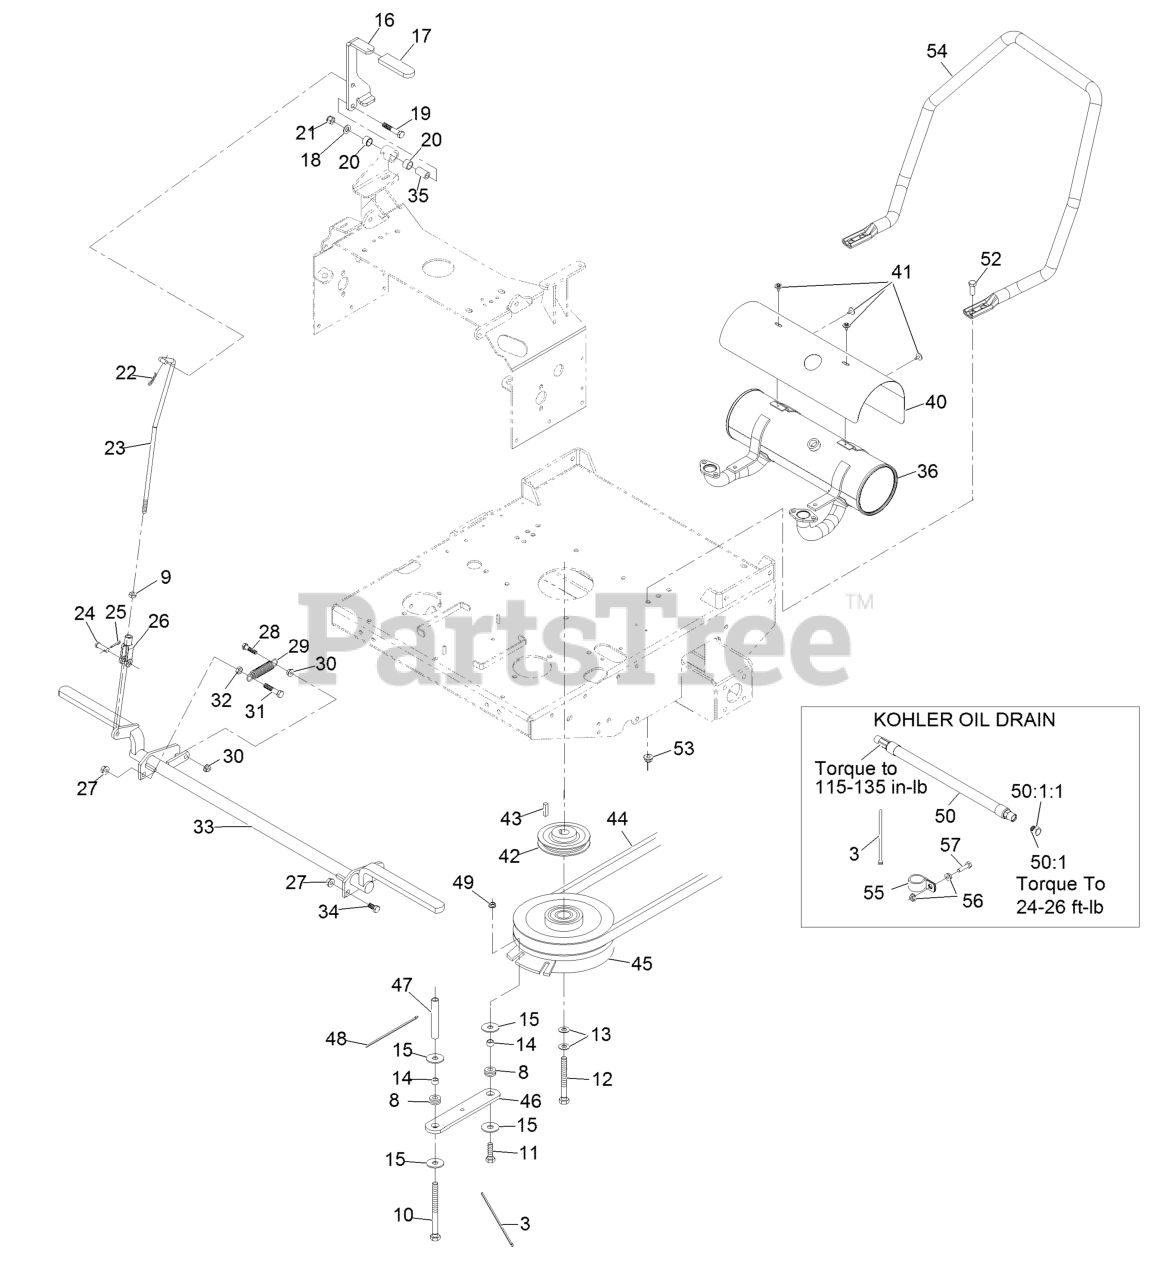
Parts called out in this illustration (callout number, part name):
3	TIE-PLASTIC
8	GROMMET
9	NUT-HJ
10	SCREW-HH
11	SCREW-HH
12	SCREW-HH
13	WASHER-SPRING
16	LEVER,PRK BRK W/DECALS
17	GRIP-LEVER
18	WASHER-FLAT
19	SCREW-HH
20	SLEEVE-BUSHING
21	NUT-LOCK, NI
22	PIN-COTTER
23	LINKAGE, PARK BRAKE
24	PIN-CLEVIS
25	PIN-COTTER
26	YOKE-LINKAGE, BRAKE
27	NUT-HHF, WHIZ
28	SCREW-HH, SPECIAL
29	SPRING-IDLER
31	SCREW-HH
32	NUT-JAM
33	WLD,BRAKE TTX
34	SCREW-HH
35	BUSHING-PIVOT
36	MUFFLER-TTX, EFI
40	SHIELD-MUFFLER,TTX EFI
41	SCREW-HH, THREAD FORMING
42	PULLEY
44	BELT,DECK DRIVE
45	CLUTCH ASM
46	STRAP-CLUTCH, BRAKE
47	SPACER,SHIELD
48	TIE-CABLE
50	OIL DRAIN HOSE ASM
50:1	PLUG-HH
50:1:1	O-RING
52	SCREW-HH
53	NUT-HF, NI
54	GUARD,AIR CLEANER
55	CLIP-LOOM
57	SCREW-HH
